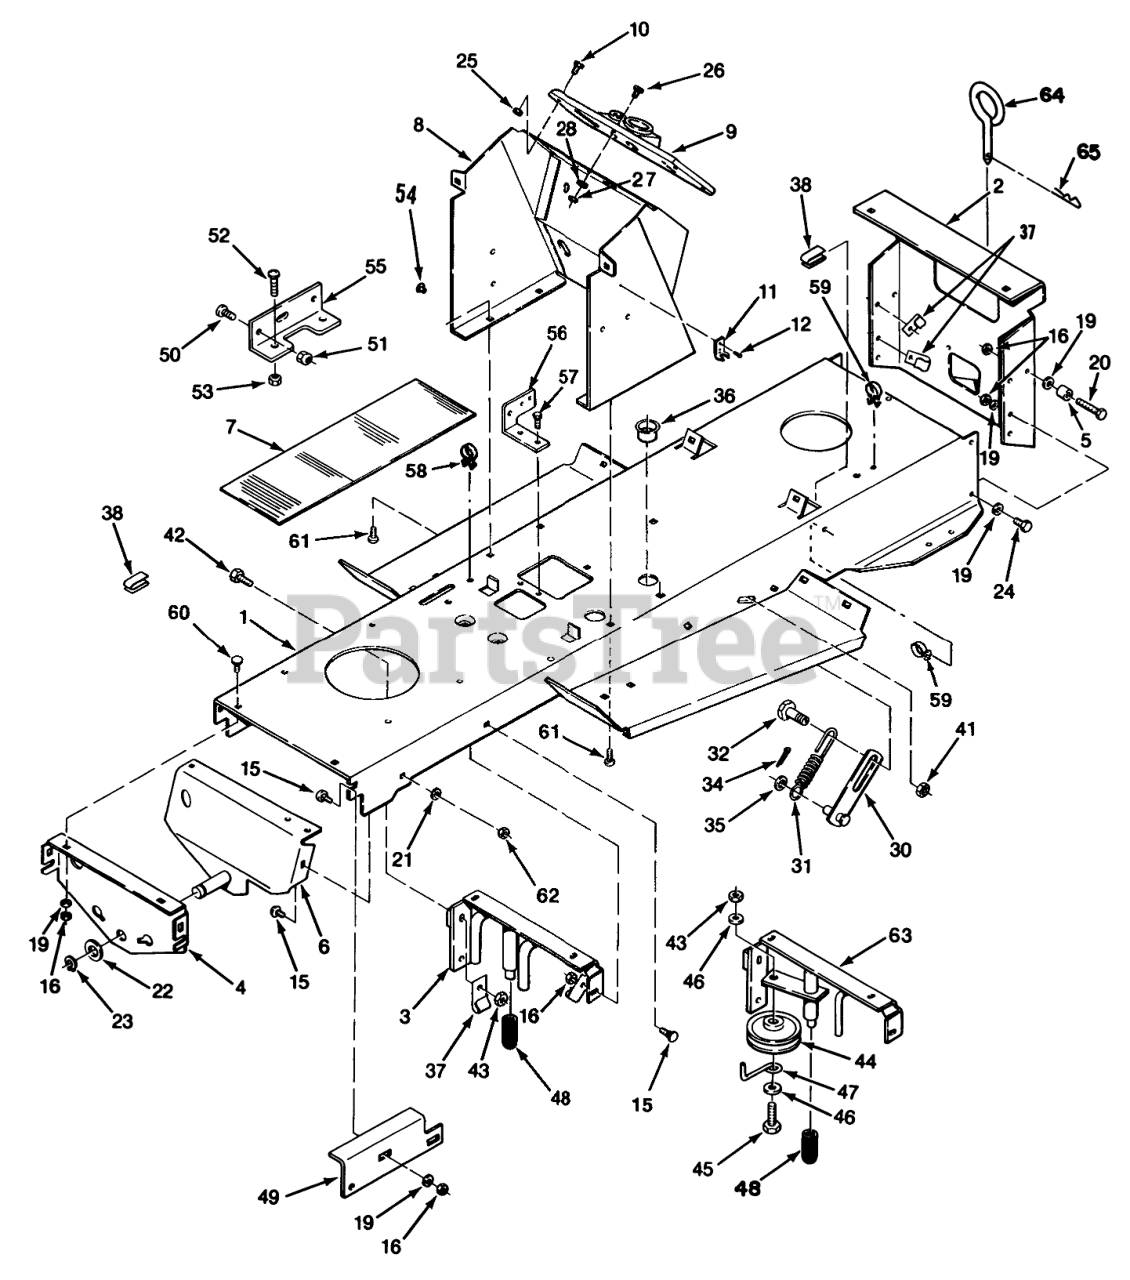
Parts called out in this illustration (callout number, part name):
1	FRAME R
2	PLATE-DRAWBAR R
3	ASS'Y-FRAME SUPPO R
4	PLATE SUPT - AXLE R
5	BEARING-CAM ROLLER
6	ASS'Y-AXLE SPT RE R
7	PAD-FOOTREST
8	WLDMT-HOODSTAND B
9	CONSOLE
10	SCREW #10X.62 PHCR
11	KEEPER-LATCH
12	POPRIVET 1/8X 1/8 BK
15	SCREW-CARR
16	NUT-LOCK, NI
19	WASHER-PLAIN
20	SCREW-HH
21	WASHER-LOCK, INTERNAL
22	WASHER
23	RING-RETAINING
24	SCREW-HH
25	Nut
26	Screw
27	NUT-HEX
28	WASHER-LOCK
30	ASSY LINK B
31	SPRING
32	CAM-ADJUST
34	PIN-COTTER
35	WASHER
36	BUSHING-NYLON 1.093
37	CLIP
38	RETAINER
41	NUT-HEX, JAM
42	SCREW-HH
43	NUT-LOCK, NI
44	IDLER PULLEY R
45	SCREW-HH
46	WASHER-FLAT
47	RETAINER BELT R
49	BRACKET L.H. R
50	Screw
51	NUT-LOCK, NI
52	Screw
53	Nut
54	PLUG-NYLON .250
55	BRKT-FUSE HOLDER B
56	BRKT-SWITCH R
57	Screw-Machine
58	CLIP-SNAP IN
59	CLIP-SNAP IN
60	CARRIAGE BOLT -4
61	Bolt
62	Nut
63	ASS'Y-FRAME SUPPO R
64	PIN-TOOL
65	Hairpin Cotter
